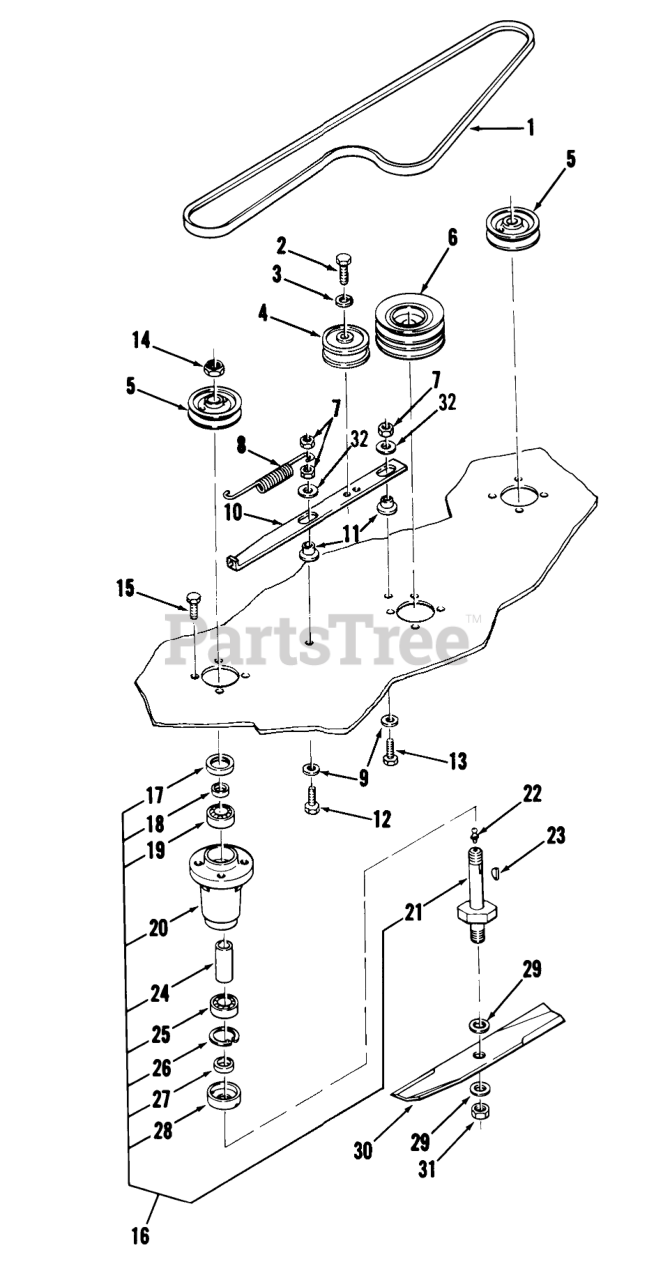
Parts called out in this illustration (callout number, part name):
1	V-BELT
2	BOLT HEX SPECIAL
3	LOCKWASHER
4	Idler Pulley
5	PULLEY-BLADE DRIVE
6	PULLEY-MOWER
7	Nut
8	SPRING-EXTENSION
9	WASHER
10	BAR-IDLER SUPPORT
11	SPACER-BUSHING
12	Bolt
13	Bolt
14	Nut
15	Bolt
16	Spindle Assembly
18	SPACER-SEAL
19	BEARING-BALL
20	HOUSING-SPINDLE
21	Spindle Shaft
22	Grease Fitting
23	Hi-Pro Key 3/16 x 5/8
24	SPACER
25	BEARING-BALL
26	Ring-Snap
27	SPACER-BLADE
28	CUP-SPINDLE
29	SpeciaI Washer
30	S/A BLADE KIT
31	Nut
32	WASHER
